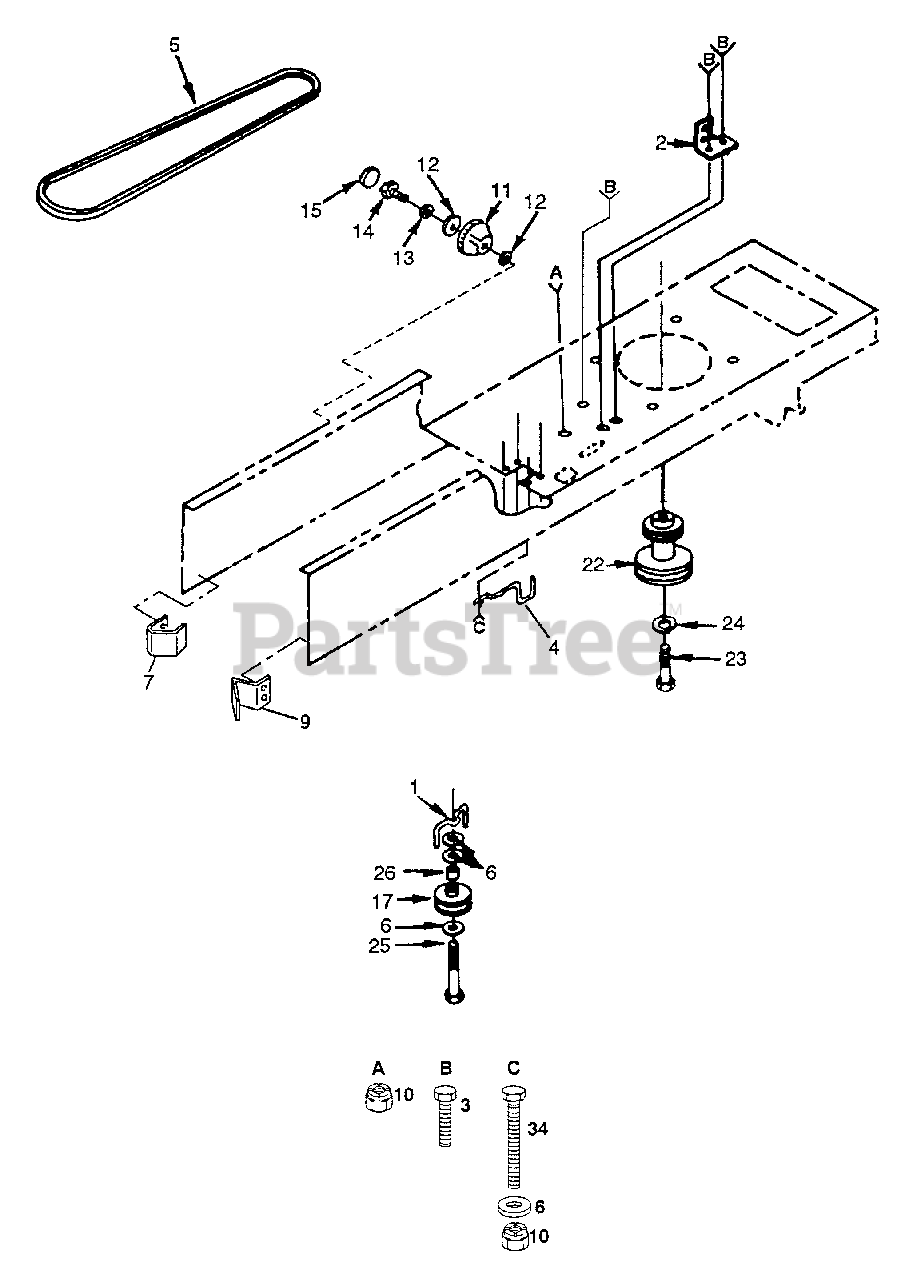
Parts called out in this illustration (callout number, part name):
1	Keeper, Belt
2	Bracket, Switch
3	Screw, Tap. Hex H d. #10 - 24 x 1/2
4	Keeper, Belt, Engine
5	V-Belt, Drive
6	Washer 13/32 x 13/16 x 12 Ga.
7	Keeper, Belt L.H.
9	Keeper, Belt R.H.
10	Nut, Crownlock 3/8 - 16
11	Scale, Indicator Height
12	Washer 11/32 x 1-1/2 x 10 Ga.
13	Washer, Lock Hvy. Helical Spring 5/16
14	Bolt, Hex 5/16-18 x 1
15	Plug, Hole
17	Idler, Flat
22	Pulley, Engine
23	Bolt, Hex 7/16 - 20 x 1 - 1/4 G8
24	Washer, Lock
25	Bolt, Hex 3/8 - 16 x 2 - 3/4
34	Bolt, Hex 3/8 - 16 x 1
